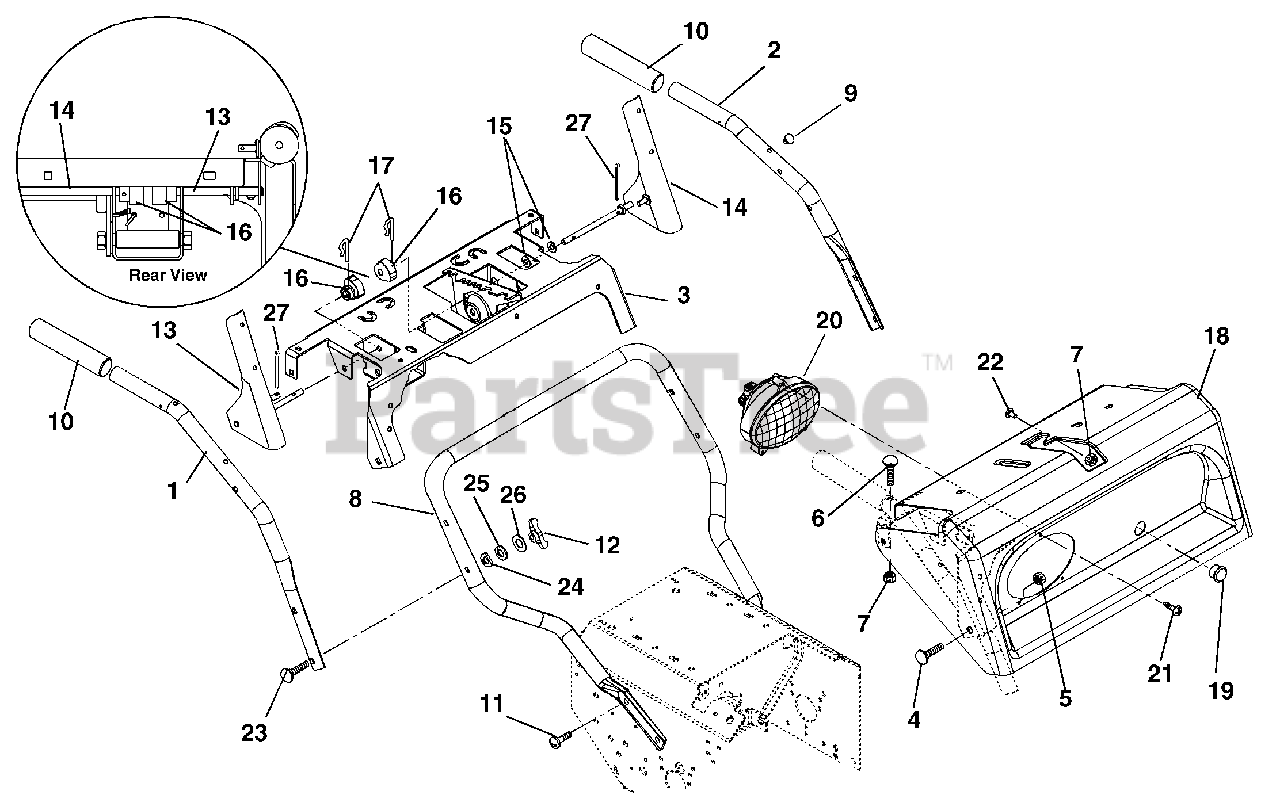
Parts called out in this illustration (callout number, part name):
1	HANDLEBAR, UPPER-RH
2	HANDLEBAR, UPPER-LH
3	PANEL, SUB
4	@BLT-RDHDSQNK .31-18X1.50 G5YZ
5	@NUT-LK-CTR .31-18 YWZC
6	BLT-RDHDXLSQNK.25-20X1.25 G5ZC
7	@NUT-LK-CTR .25-20 YWZC
8	HANDLEBAR, LOWER
10	HANDLE GRIP
11	BLT-SERHFWH .38-16X.75 YWZC
12	KNOB - WING .312-18 UNC
13	LEVER, RH-COATED
14	LEVER, LH-COATED
15	@WSHR-FL-STL.344X.688X.065YWZC
16	CAM, INTERLOCK
17	PIN, SPRING CLIP
18	PANEL W/DECAL - 824
19	SNAP BUSHING
20	HEADLAMP, OVAL W/ 1156 BULB
21	SCR-TAP 10-16X.75 HI-LO PPH
22	BLT-RDHDSQSHNK.25-20X.50 YWZC
23	@BLT-RDHDSQNK .31-18X2.25 G5YZ
24	WASHER,SADDLE-.320 X.937 X.062
25	WSHR-LK .312X.097 HVY YWZC
26	@WSHR-FL-STL.38X.875X.083 YWZC
27	@PIN-CTR .09X.75 EXTPRSQCT YWZ
